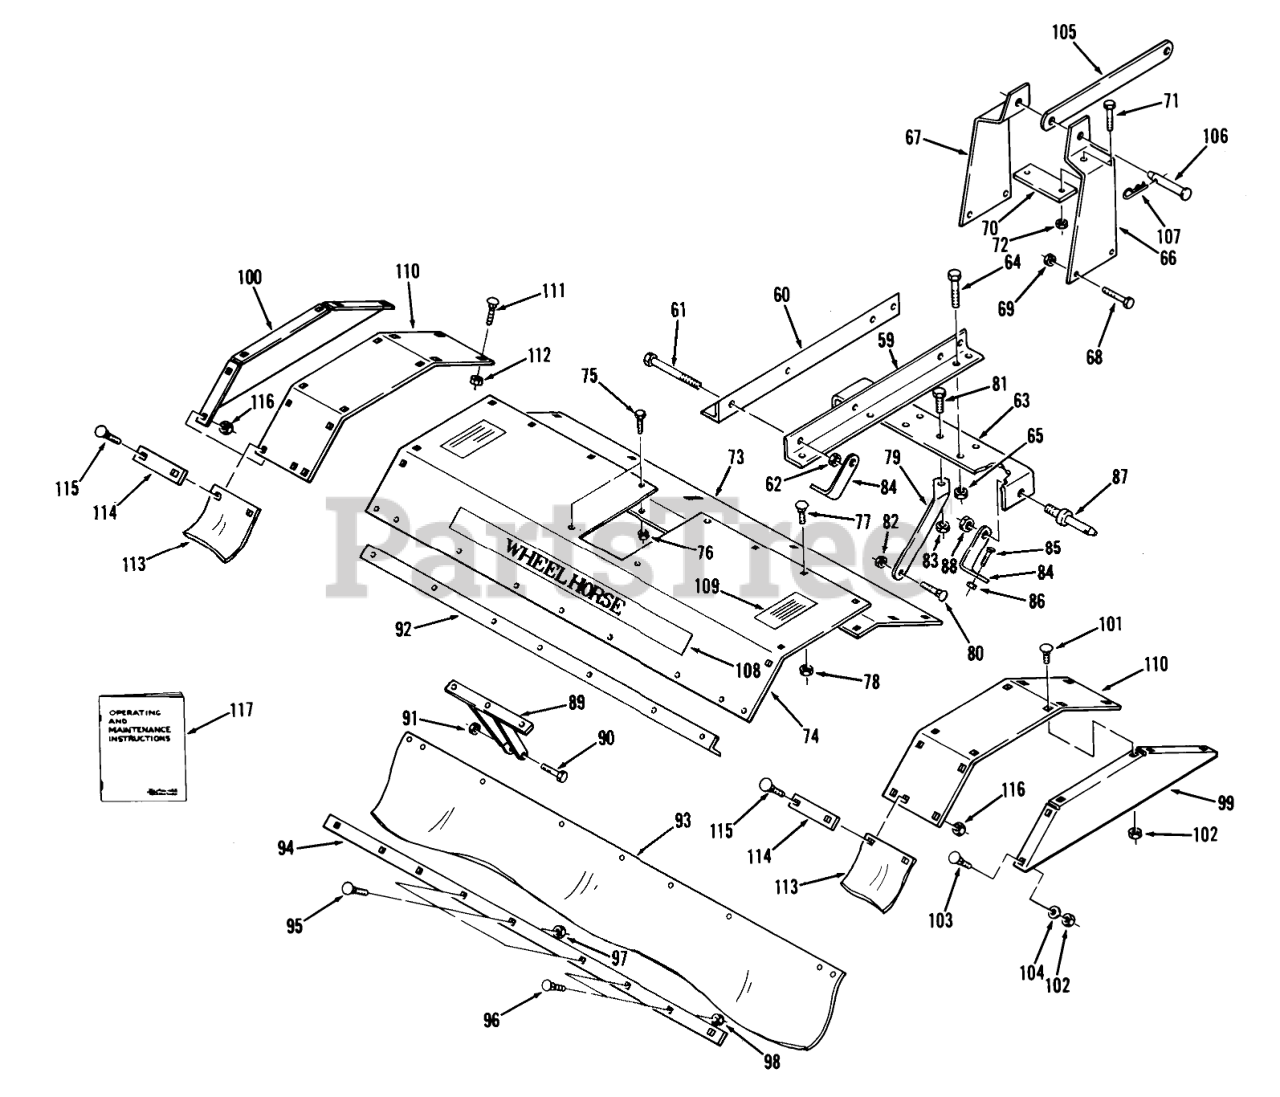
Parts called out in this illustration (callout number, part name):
59	R.H. Tiller Support Angle
60	L.H. Tiller Support Angle
61	Bolt 1/2-13 x 6 1/2
62	Nut
63	Lower Hitch Bar
64	Hhcs
65	Nut
66	R.H. Upper Hitch Plate
67	L.H. Upper Hitch Plate
68	Bolt
69	NUT
70	Strap
71	Bolt
72	Nut
73	Front Tine Shield
74	Rear Tine Shield
75	BOLT
76	NUT
77	Bolt
78	Nut
79	Front Brace
80	Bolt
81	Bolt
82	NUT
83	Nut
84	Tine Shield Brace
85	Bolt
86	Nut
87	Lower Link Pin
89	Spring
90	Bolt
91	NUT
92	Tine Shield Angle
93	GUARD-REAR TINE
94	Strap
95	Bolt
96	Bolt-Carriage
97	NUT
98	Nut
99	R.H. Tine End Cover
100	L.H. Tine End Cover
101	Bolt
102	Nut
103	Bolt-Carriage
104	WASHER 5/16 SAE
105	LINK UPPER
106	PIN HITCH UPPER LINK
107	Hairpin
108	Decal
109	Caution Decal
110	Cover-Extension
111	Bolt
112	Nut
113	Tine Guard
114	Strap
115	Bolt-Carriage
116	Nut
117	Operating and Maintenance Instructions
